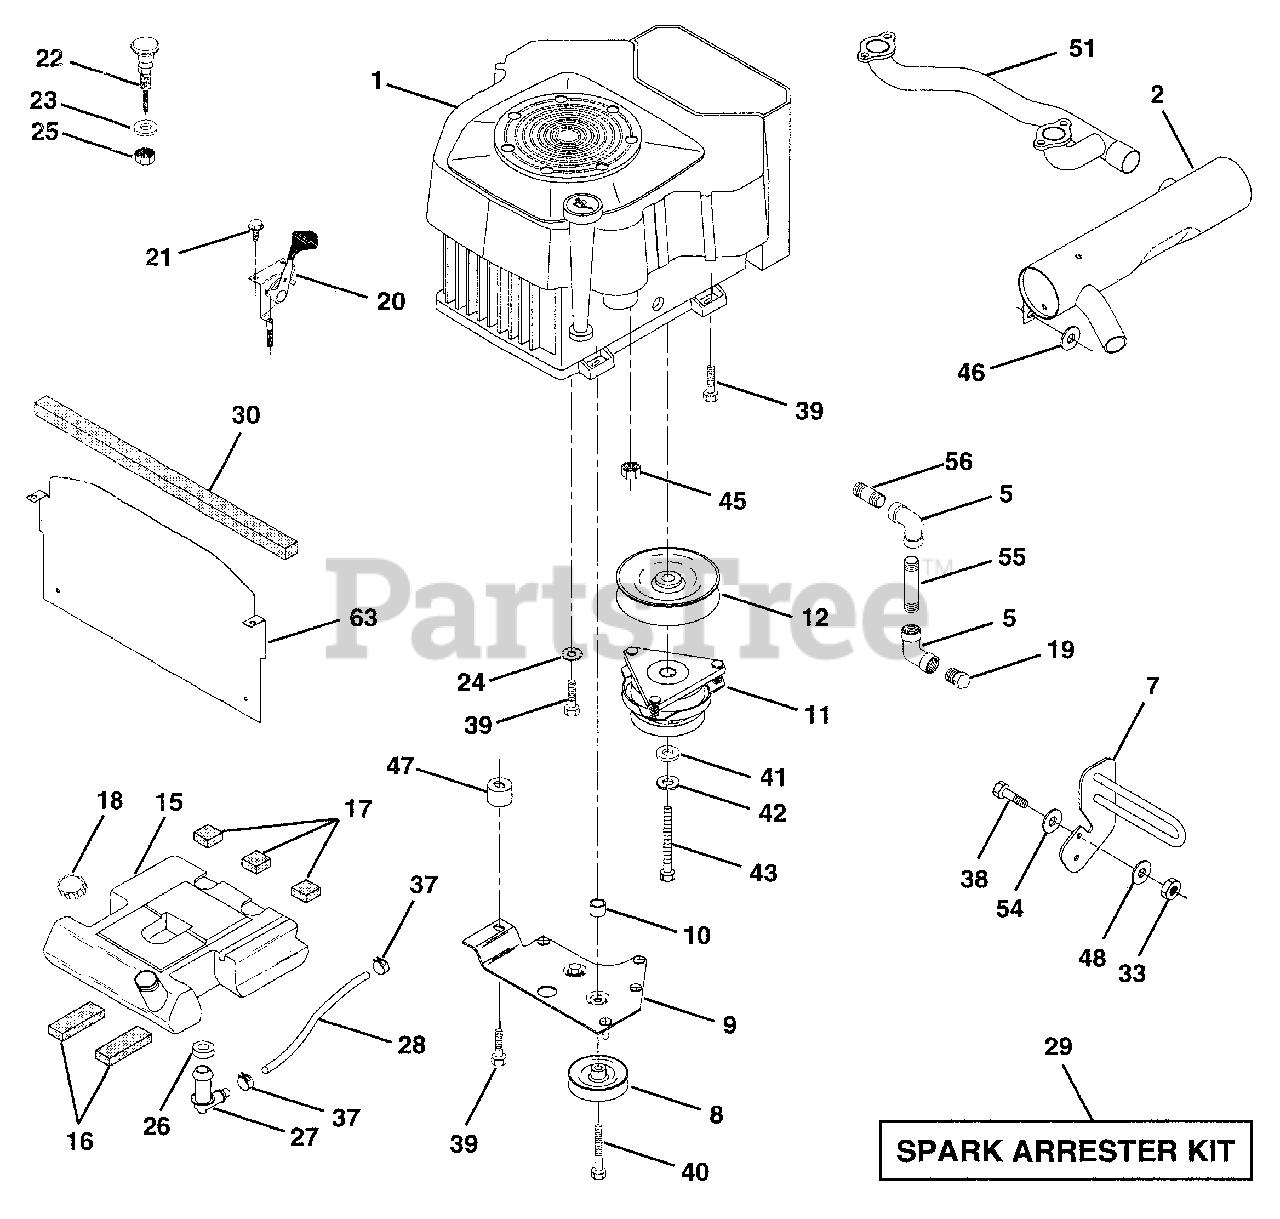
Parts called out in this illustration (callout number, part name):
2	Muffler VGT Cylinder
5	Elbow STD 90 Degree 3/8-18 NPT
7	Muffler Assembly Guard
8	Pulley V-Idler
9	Stop Keeper Asm VGT
11	Clutch Electric
12	Pulley Engine VGT Elect Clutch
15	Tank Fuel W/Sym Vented
16	Pad Spacer
17	Pad Spacer
18	Cap Asm Fuel W/Sym Vented
19	Plug Oil Drain
20	Control Throttle
21	Screw Hex Thd Cut 1/4-20 X 5/8
22	Control Choke
23	Washer 13/32 X 13/16 x 16 Ga
24	Washer Ext Tooth 3/8
25	Nut Keps 3/8-24 UNF
26	Bushing
27	Stern Tank Fuel
28	Fuel Line
29	Spark Arrester Kit
30	Strip Foam 18"
33	Nut, Hex W/Ins. 3/8-16 UNC
37	Clamp Hose
38	Bolt, Fin Hex 3/8-16 UNC x 1-1/2
39	Screw TT 3/8-16 x 2-1/4 UNC
40	Screw TT 3/8-16 x 4 UNC
41	Washer 1-1/2 OD X 15/32 ID X .250
42	Washer Lock 7/16
43	Bolt Hex 7/16-20 X 4-1/4 Ga 5
45	Nut Flange 1/4-20 Starter Nut
46	Washer 13/32 x 1 x 16 Ga.
47	Spacer Engine
48	Washer 13/32 x 1-1/4 x 7 Ga.
51	Pipe Crossover
54	Washer Flat 13/32 x 7/8 x 14 Ga.
55	Nipple, Pipe 3/8 NPT x 4-1/2
56	Nipple, Pipe 3/8 NPT x 1.00
63	Shield, Heat VGT YP/Husq.
